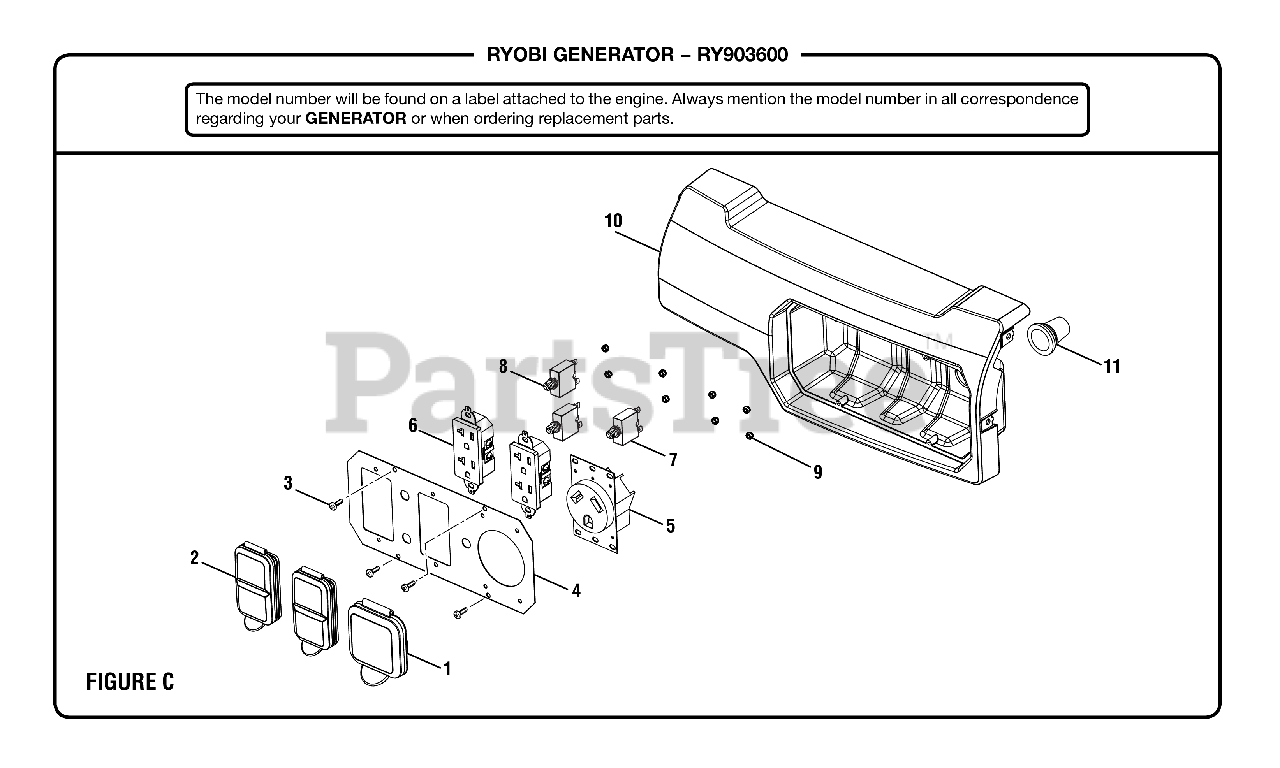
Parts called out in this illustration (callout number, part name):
1	Outlet Cover
2	120 Volt Receptacle Rain Cover
3	Screw (1/4-20 x 1 in., T30 Torx Hd.)
4	Front Panel
5	Twist Lock Receptacle (120 Volt, 30 Amp)
6	120 Volt Duplex Receptacle (BM903611)
7	Circuit Breaker 30 Amp 1 Pole
8	Circuit Breaker (20 Amp, 125 Volt)
9	Lock Nut (M4)
10	Control Box (Back Panel)
11	Wiring Rubber Boot
